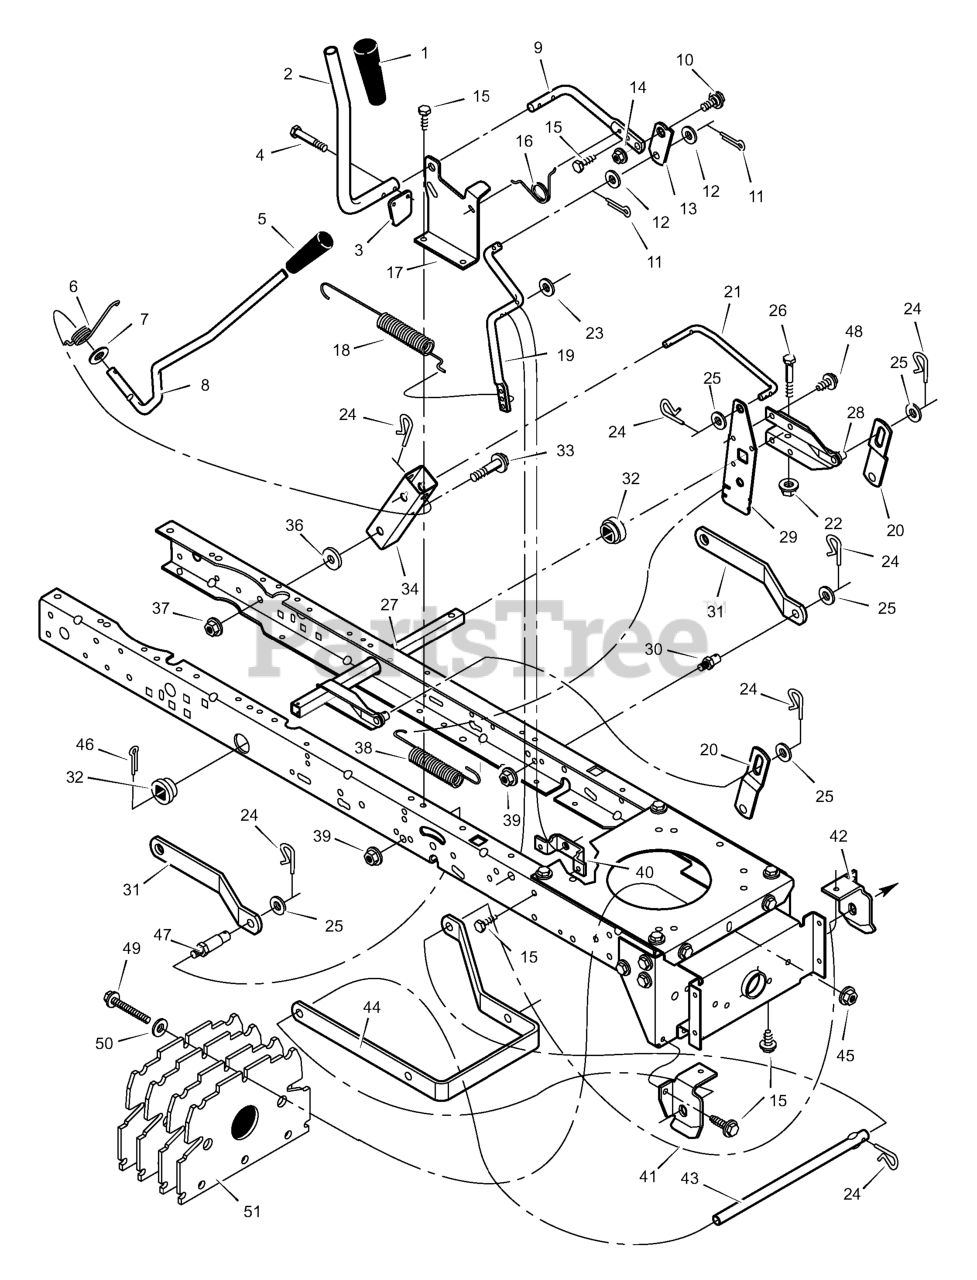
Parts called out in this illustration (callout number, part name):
1	Grip
2	Handle, PTO
3	Pad, Switch
4	Screw, Hex
5	Grip
8	Lever, Lift
9	Lever, PTO
10	Bolt, Shoulder
11	Pin, Cotter
12	Washer
13	Link, PTO
14	Nut, Flange
17	Bracket, PTO
19	Crank, PTO
20	Link, Lift
21	Link, Lift Handle
22	Nut, Flange
24	Pin, Hair
26	Bolt, Hex
27	Arm Assembly, Right Lift
28	Arm, Right Lift
29	Plate, Lift Arm
30	Pin
31	Bracket, Rear Suspension
32	Bushing, Lift Tube
33	Bolt, Shoulder
34	Bracket, Pivot
37	Nut, Flange
39	Nut, Flange
40	Bracket, PTO
41	Hanger, Right Deck
42	Hanger, Left Deck
43	Rod, Hanger
44	Hanger, Front
45	Nut, Flange
46	Pin, Cotter
47	Pin, Threaded Shoulder
49	Bolt, Hex
51	Plate, Weight
